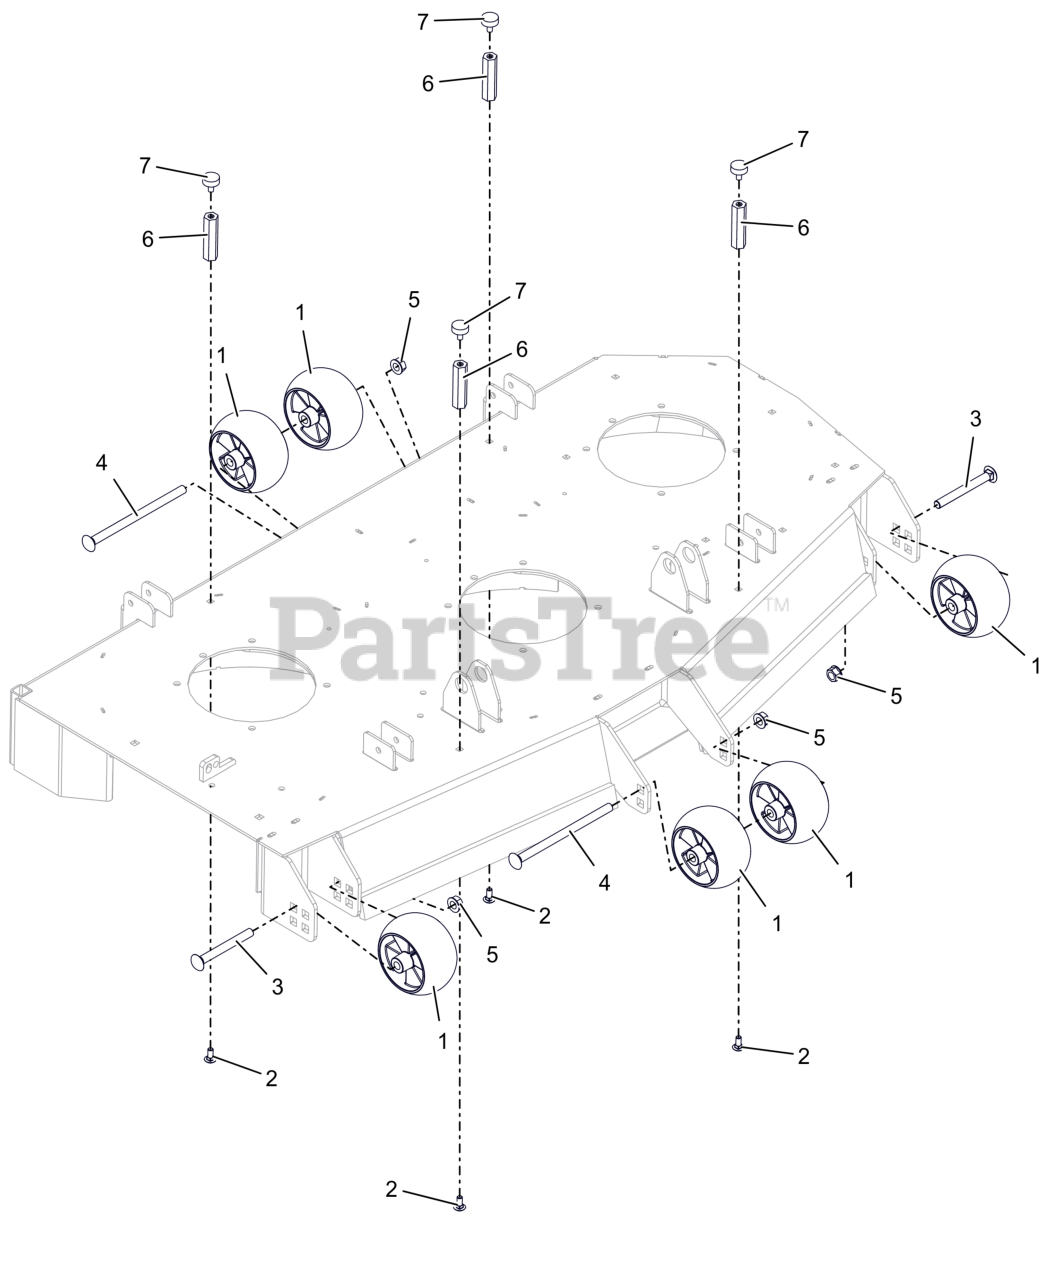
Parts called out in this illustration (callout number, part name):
1	WHEEL, ANTI SCALP - 5X3 CTR W/RIBS
2	BLT, RHSN .31-18X.75 G5 ZCC LT
3	BLT-RHNS .50-13X4.50 G5 ZCC NS
4	BLT-RHSN .50-13X8.00 G5 ZCC NS
5	NUT-LK-CTR-FLG .500-13 GG ZCC
6	NUT, COUPLING .31-18 X 3.00
7	BUMPER, RUBBER
